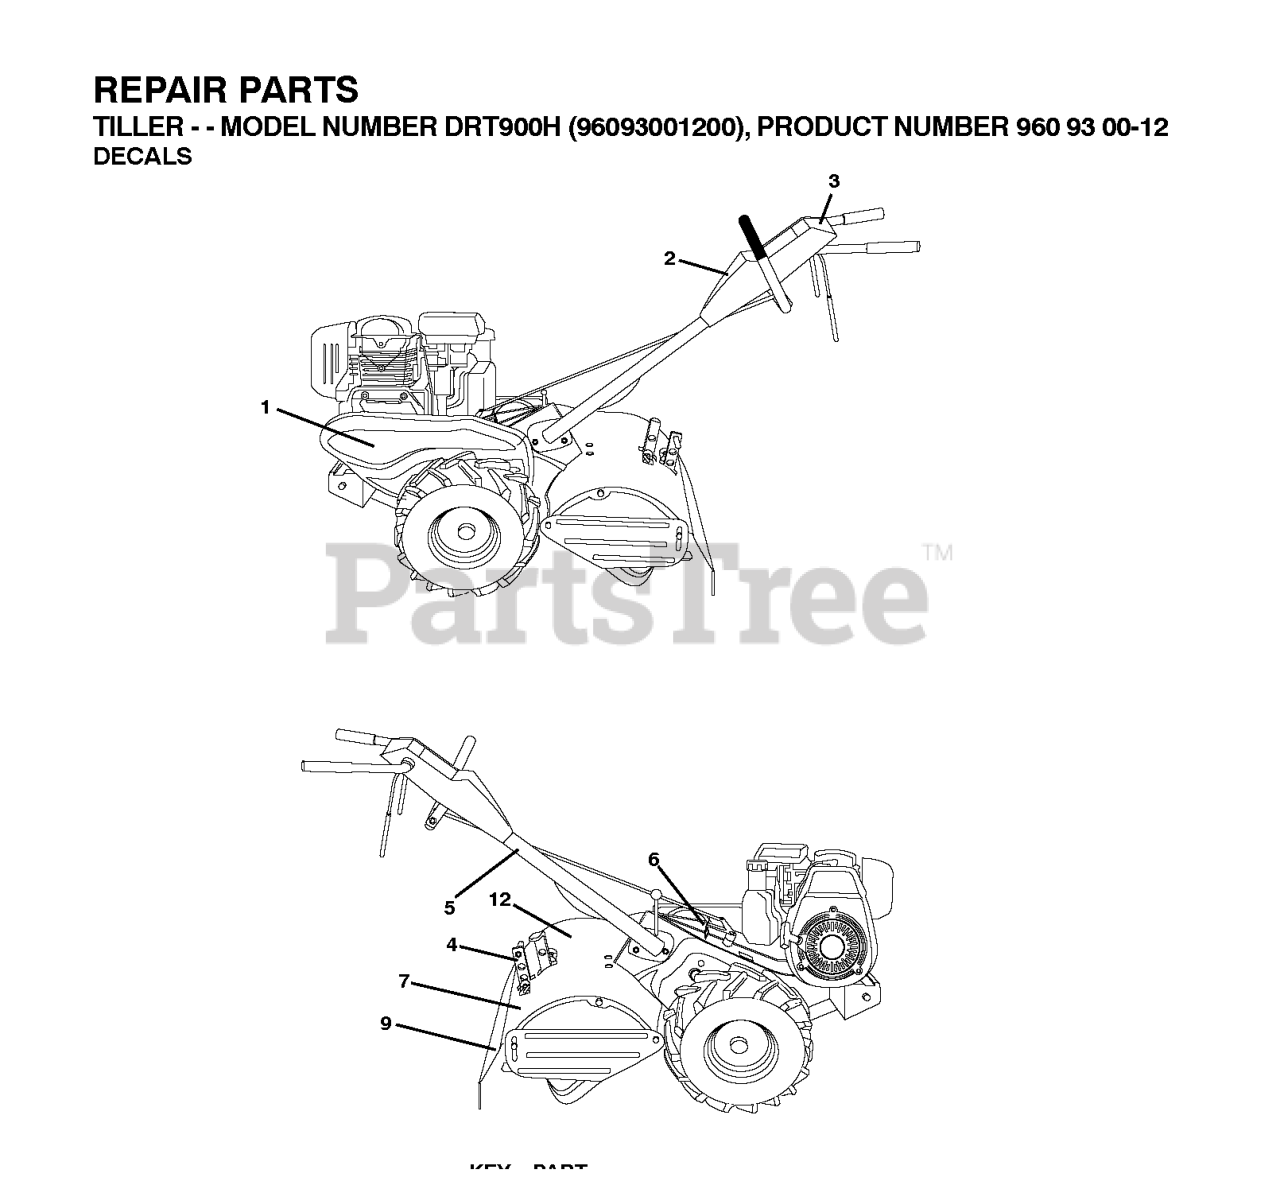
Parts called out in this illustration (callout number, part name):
1	RP.DECAL.BADGE.170MM.TEXTLOGO
2	DECAL.CONSOLE.DRT900H.HUSVARNA
3	DECAL.CONSOL.INST.DRT
4	DECAL.SHIELD.TN.DRT17.HUSQ.008
5	DECAL TI (2 2)
6	DECAL.SHIFT.INDICATOR.DRT
7	DECAL.REVERSE.HUSQ
9	DECAL.DRT.WARN.ENG/F
12	DECAL.FORWARD.HUSQ
